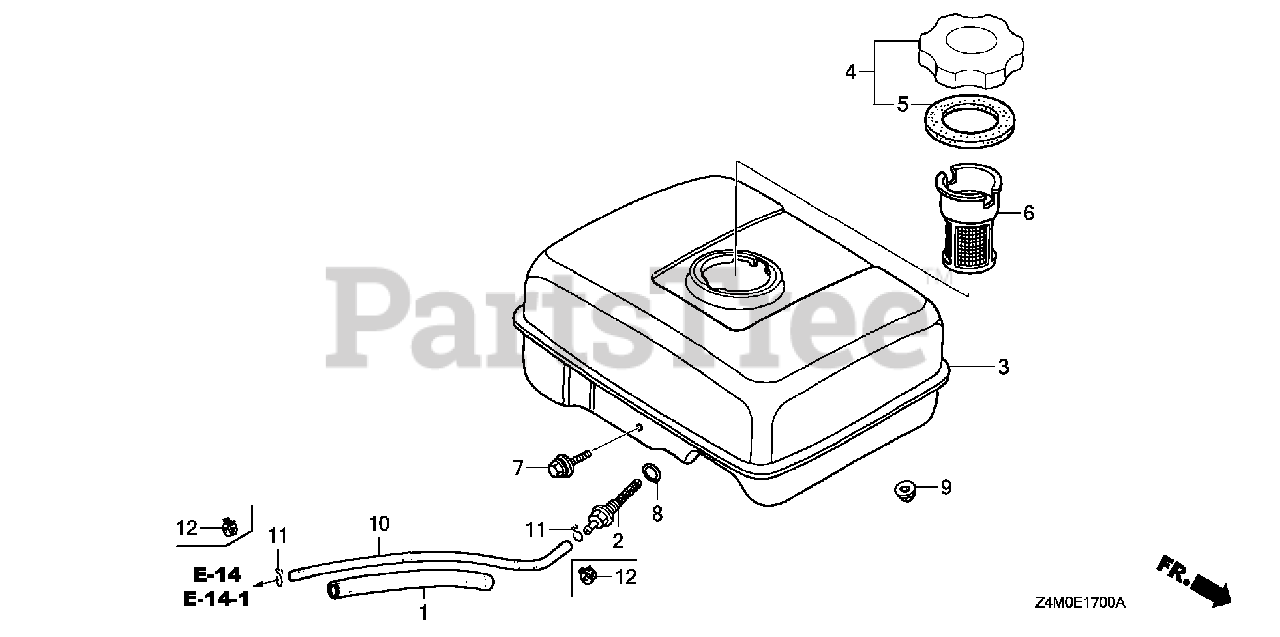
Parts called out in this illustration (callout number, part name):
1	RUBBER, SUPPORTER (107MM)
2	JOINT, FUEL TANK
3	TANK, FUEL *NH1* (Honda Code 7983620). (BLACK)
3	TANK, FUEL *NH31* (Honda Code 7983646). (MCKINLEY WHITE)
4	CAP, FUEL FILLER
5	GASKET, FUEL FILLER CAP
7	BOLT, FLANGE (6X29)
8	O-RING (13.5X1.5) (ARAI)
9	NUT, FLANGE (6MM)
10	TUBE, FUEL (4.5X140) (FKM)
10	BULK HOSE, FUEL (4.5X3000) (Honda Code 5137104). (4.5X140)
11	CLIP, TUBE (B8)
12	CLIP, TUBE (D8)
